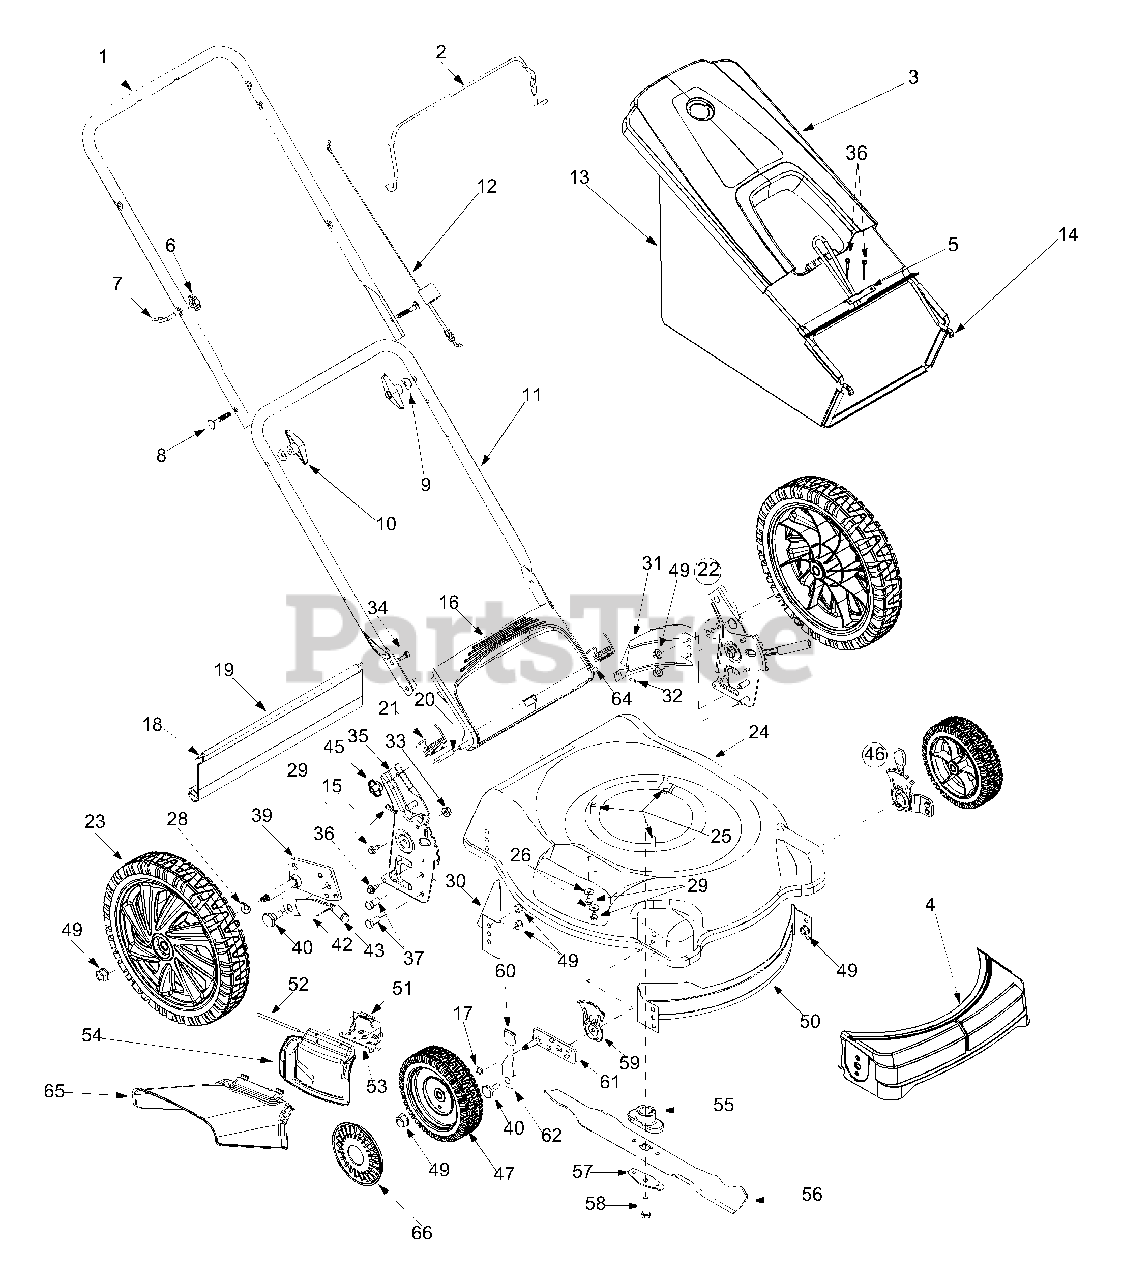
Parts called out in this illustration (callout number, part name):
2	Control Handle
3	Hardtop Cover
4	Front End Cover
7	Rope Guide
8	Carriage Bolt 5/16-18 x 2"
9	Shoulder Washer .320 ID x .930 OD
10	Wing Nut
12	Control Cable 37.25"
12	Control Cable 40"
12	Control Cable 53"
13	Grass Bag
15	Hairpin Clip
16	Grass Bag Door
17	Wave Washer.510 x.750 x.017
18	Wire Rod
19	Trailshield
20	Spacer .375 O.D. x .50 I.D. x 1.02"
21	Torsion Spring - RH
21	Torsion Spring - LH
22	Handle Bracket Assembly - RH
22	Handle Bracket Assembly - LH
23	Rear Wheel: 8-Spoke Bar Gray 12 x 2
23	Rear Wheel: Zag Trd. Gray 12 x 2.125
23	Rear Wheel: Zag Trd. Yellow 12 x 2.126
26	Bell Washer .265 ID x .75 OD
28	Spring Washer.500 x 1.00 x.022
29	Screw 1/4-20 x.500
30	Rear Baffle - RH
31	Rear Baffle - LH
32	Tap Screw 1/4-14 x .625.
33	Flange Lock Nut 3/8-16
34	Hex Carriage Screw 1/4-20
35	Handle Bracket Assembly - RH
35	Handle Bracket Assembly - LH
36	TT Screw 1/4-14 x .625
37	Hex Screw 3/8-16 x 0.75
38	Hex Cap Screw 3/8-16 x 1.0
39	Pivot Bar Assembly - RH
39	Pivot Bar Assembly - LH
40	Shoulder Screw
42	Spring Lever
43	Grip: Spring Lever
45	Wing Nut
46	Front Height Adjuster Assembly - RH
46	Front Height Adjuster Assembly - LH
47	Front Wheel: 8-Spoke Bar Gray 8 x 2
47	Front Wheel: Zag Trd. Gray 8 x 2.125
49	Flange Lock Nut 3/8-16
50	Front Baffle
51	Torsion Spring
52	Hinge Pin
53	Hinge Mounting Bracket
54	Mulching Plug
55	Blade Adapter
56	Blade: 21" Mulching
57	Blade Bell Support
58	Hex Cap Screw 3/8-24 x 1.5
59	Height Adjustment Plate
60	Knob
61	Pivot Bar Assembly - RH
61	Pivot Bar Assembly - LH
62	Spring Lever
64	Chute Door Pivot Rod
65	Side Discharge Deflector
